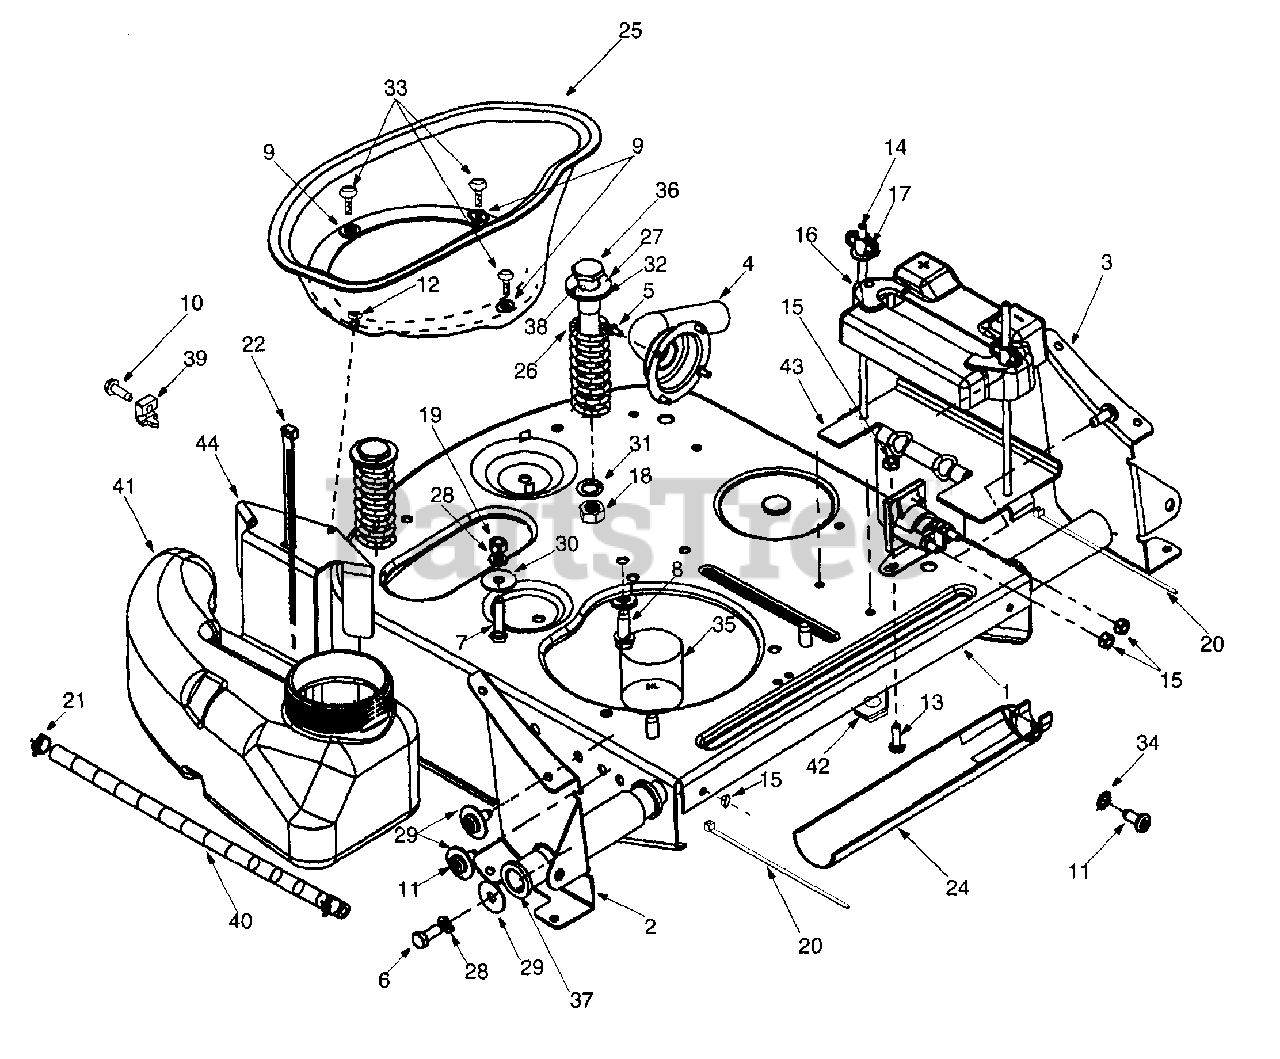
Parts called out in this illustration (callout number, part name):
5	Hex Fl. Screw #8-32 x 0.375
6	Hex Screw 5/16-24 x .75" Gr.5
7	Hex Screw 5/16-24 x 1.5" Gr.5
8	Hex Washer Head TT Screw 3/8-16 x 1.0"
9	Hex Slot Sems Screw #10-32 x 0.38
10	Hex Washer TT Screw #10-32 x 0.625"
11	TT Screw 5/16-18 x 0.75"
12	Machine Screw #10-32 x 0.5"
13	Hex Screw 1/4-20 x 0.75"
14	Battery Hold-down Rod
15	Hex Sems Nut 1/4-20
16	Battery Cover
17	Wing Nut with Bell Washer
19	Hex Nut 5/16-24 Gr.5
22	Cable Tie
24	Oil Drain Sleeve
26	Compression Spring
27	Rubber Washer
28	Lock washer
29	Flat Washer
35	Motor Oil
36	Shoulder Screw
37	Flange Bearing
38	Flange Bearing
39	Throttle Casing Clamp
40	Fuel Line Hose
